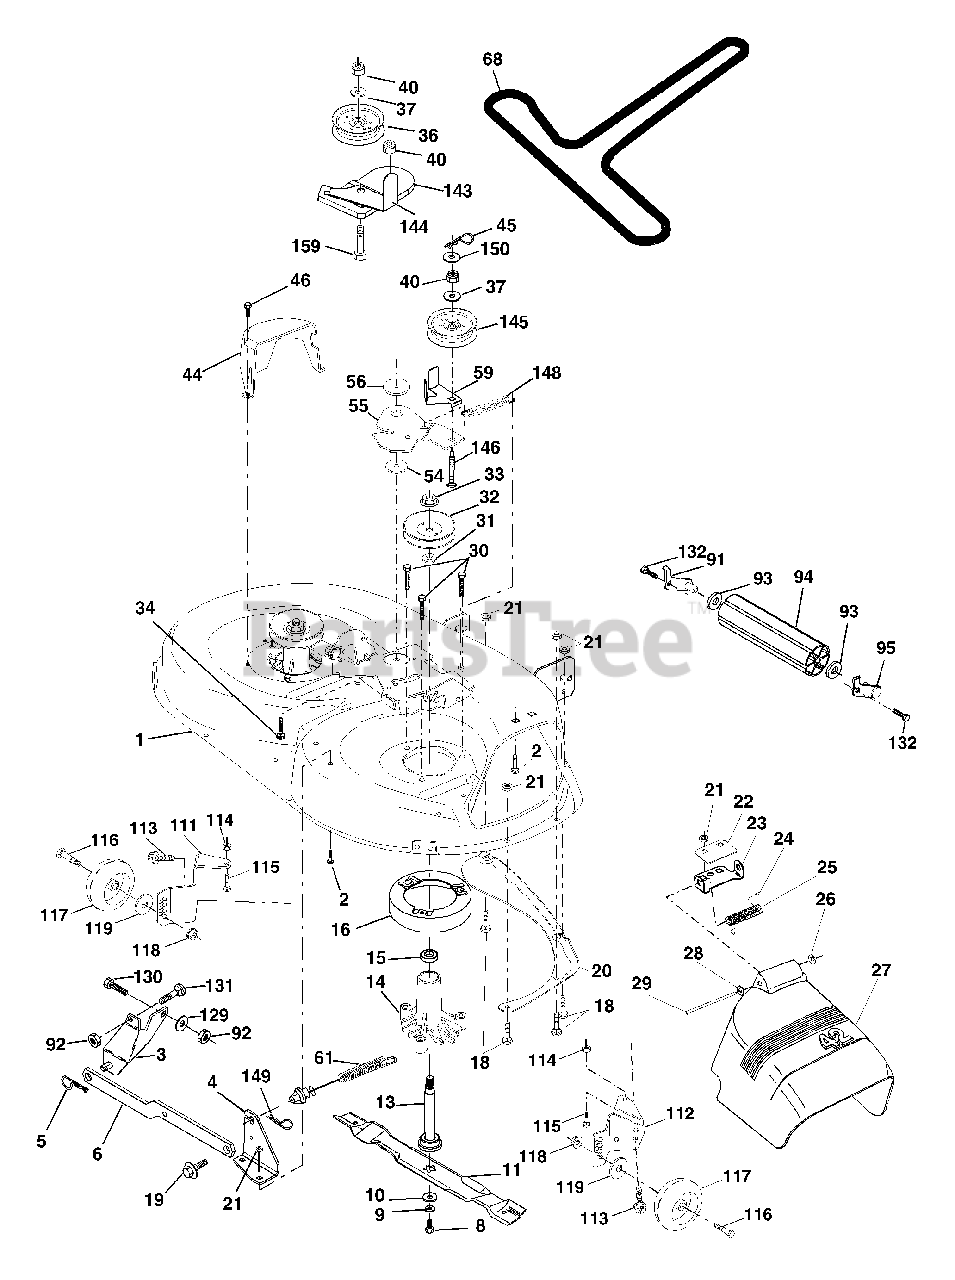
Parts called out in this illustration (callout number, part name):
1	Mower Deck Assembly, 42"
2	Bolt
3	Bracket Assembly,Sway Bar, Front
4	Bracket Sway Bar 38/42" Deck
5	Retainer Spring
6	Bar Sway Deck
8	Bolt, Hex 3/8-24 x 1.25 Gr. 8
9	Washer, Lock
10	Washer, Hardened
11	Blade Mower 42" High Perf.
13	Shaft Assembly, Mandrel, Vented
14	Housing, Mandrel, Vented
15	Bearing, Ball, Mandrel
18	Bolt, Carriage 5/16-18 x 5/8
19	Bolt, Shoulder
20	Baffle, Vortex
21	Nut Crownlock 5/16-18 UNC
22	Stiffener Bracket
23	Bracket, Deflector
24	Cap, Sleeve
25	Spring, Torsion, Deflector
27	Shield, Deflector
28	Washer 11/32 x 5/8 x 16 Ga.
29	Rod, Hinge
30	Screw Thdrol Roll Hex
31	Washer, Spacer
32	Pulley, Mandrel
33	Nut, Toplock, Flanged
36	Pulley, Idler, Flat
37	Washer 13/32 x 13/16 x 16 Gauge
40	Nut Crownlock 3/8-16 UNC
44	Guard, Mandrel, L.H.
45	Retainer
46	Screw, Thd. Roll 1/4-20 x 5/8
54	Washer, Hardened
55	Arm, Idler
56	Spacer, Retainer
59	Guard, TUV Idler
61	Spring Ext Elect Clutch 42" Dck
91	Bracket Asm Noseroller Lh
92	Nut Lock Hex w/Ins. 3/8-16 Unc
93	Washer 17/32 x 7/8 x 16 Ga.
94	Roller Nose 38"-50"
95	Bracket Asm Noseroller Rh
111	Bracket, Gauge, Wheel L.H.
112	Bracket, Gauge, Wheel R.H.
113	Screw 3/8-16 x .625
114	Nut, Hex, Keps 5/16-18 UNC
115	Bolt, Carriage 5/16 -18 x 5/8
116	Bolt, Shoulder
117	Wheel, Gauge
118	Nut, Centerlock 3/8-16
119	Washer 3/8 x 7/8 x 14 Gauge
129	Washer 13/32 x 13/16 x 12 Ga.
130	Bolt Fin Hex 3/8-16 UNC x 1 Gr. 5
131	Bolt RDHD 3/8-16 UNC x 1
132	Screw 3/8-16 x .75
143	Bracket Arm Idler 42"
144	Keeper Belt 42" Clutch Cable
145	Pulley Idler Flat
146	Bolt Carriage Idler
148	Spring Return Idler
149	Retainer Spring Yellow Zinc
150	Washer 9/32 x 3/4 x 16 Ga.
159	Bolt Rdhd Sqn 3/8-16 UNC x 1- 3/4
